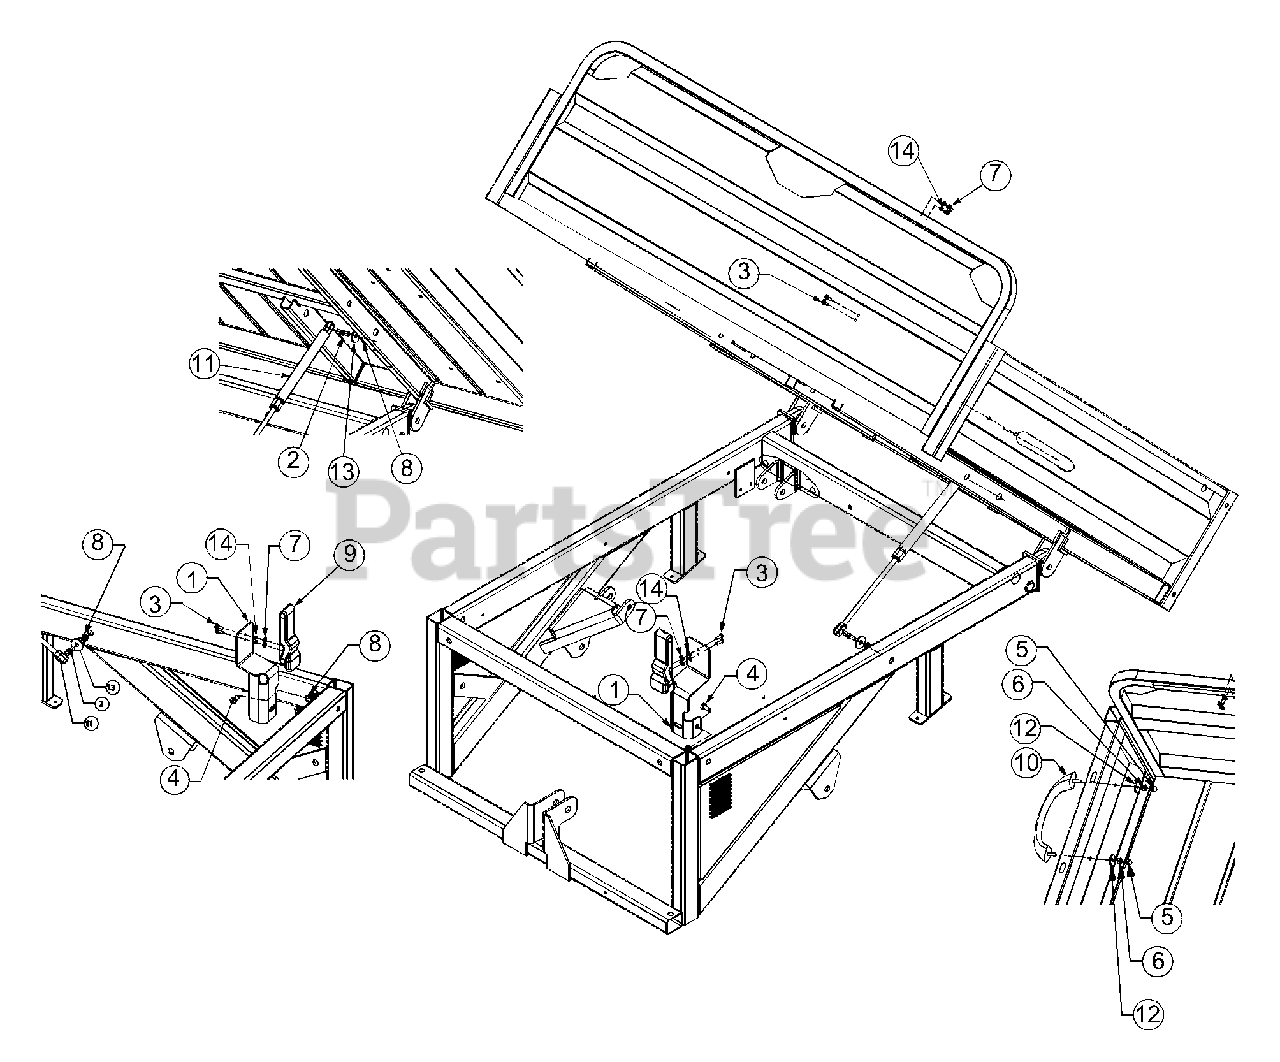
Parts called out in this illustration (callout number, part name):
1	Bracket, Bed Latch Base
2	Stud, Ball 5/16-18
3	Screw, Hex Sems, #10-32 x .62, Gr5
4	Hex Screw, 5/16-18 x .625, Gr5
5	Nut, Acorn 1/4-20 w/o Lock
6	Nut, Hexlock, 1/4-20
7	Hex Nut, 10-32
8	Nut, Insert 5/16-18
10	Handle, Bag w/Screw
11	Spring, Gas .91 Stroke
12	Washer, Flat .265 x .938 x .120
13	Washer, Flat .34 ID X1.125 OD x .12
14	Washer, Lock, #10
